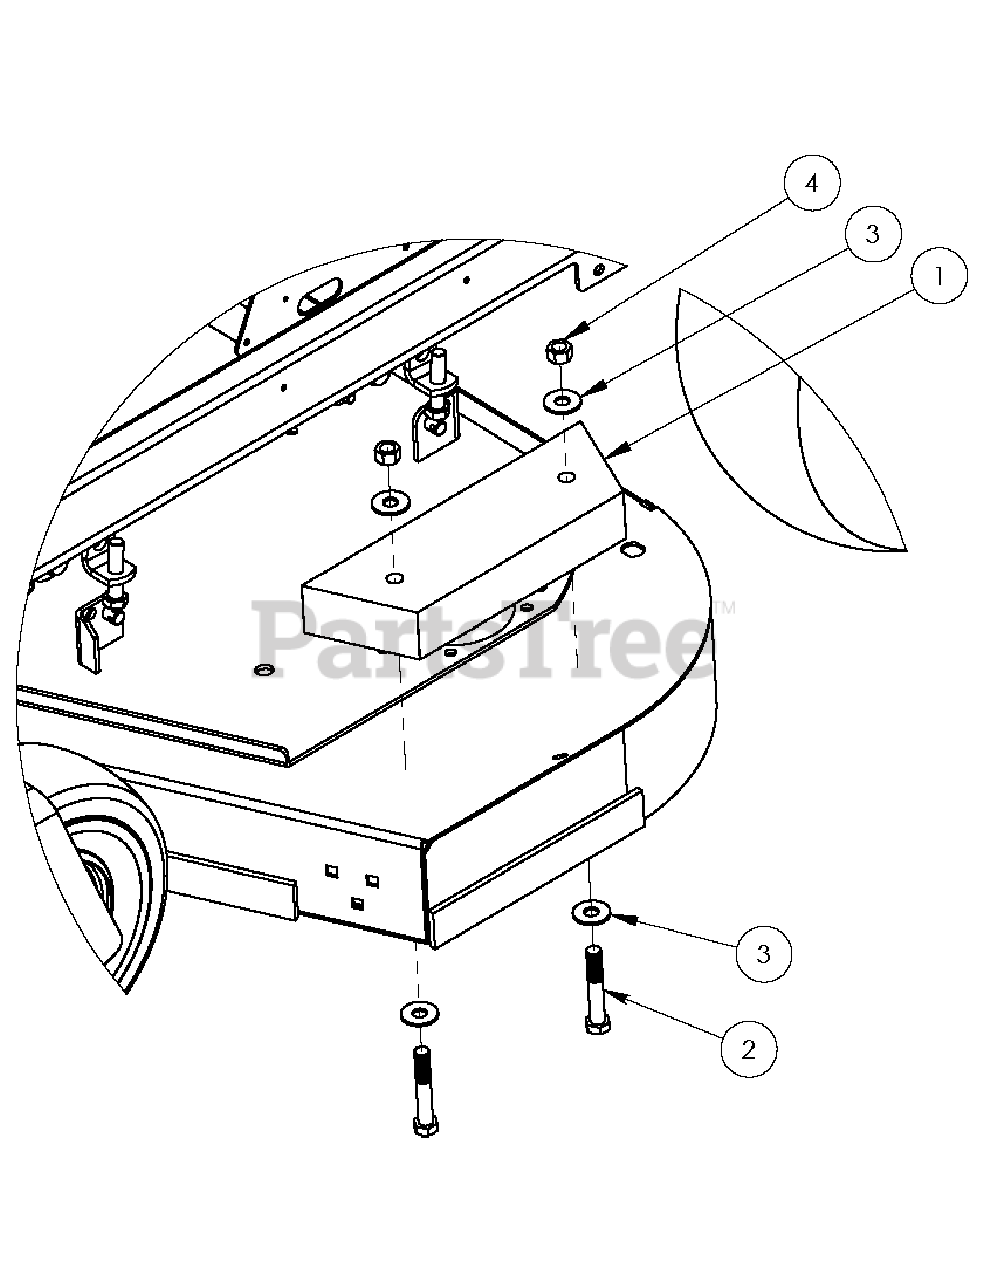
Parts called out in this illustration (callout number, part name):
2	CAP SCREW-1/2"-13 X 3"
3	FLAT WASHER-1/2"
4	HEX NUT, NYLON INSERT-1/2"-13
